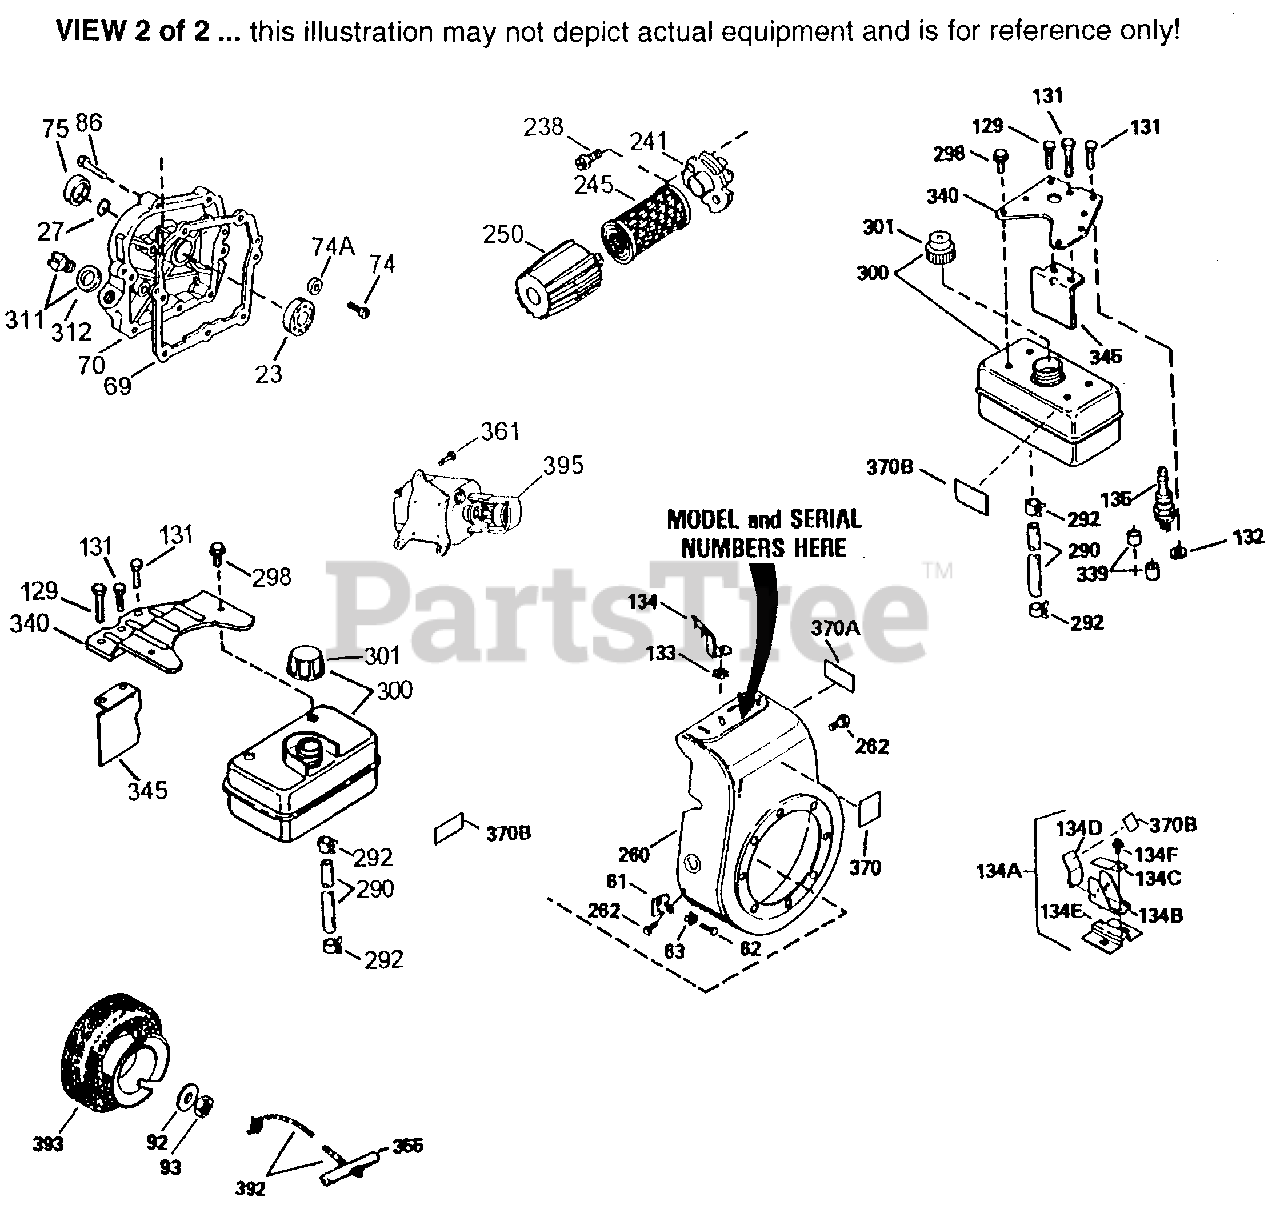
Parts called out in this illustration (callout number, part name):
19D	Extension Spring Ass'y. (Incl. 213)
23	Ball Bearing
27	Bearing Retainer
28	Lock Nut, 8-32
35	Screw, 10-32 x 3/4"
36	Lock Washer #8
37	Lock Nut, 10-32
38	Retaining Ring
64	Screw, T-30, 1/4-20 x 1/2"
64A	Washer
69	* Cylinder Cover Gasket
70	Cylinder Cover Incl. 72 thru 83 & 311
72A	Oil Drain Plug (Sq. hd., 1/4-18)
74	Screw, 10-24 x 9/16"
75	Oil Seal
86	Screw, 1/4-20 x 1-1/4"
92	Belleville Washer
93	Flywheel Nut
130A	Screw, 5/16-18 x 1-1/2"
130B	Screw, 5/16-18 x 1-1/2"
181	Screw, 1/4-28 x 1-11/16"
213	Screw, 10-32 x 3/8"
238	Screw, 8-32 x 3/8"
245	Air Filter (Paper) also available in Packaged Part #740029B
250	Air Cleaner Cover
260	Blower Housing
262	Screw, 1/4-20 x 1/2"
290	Fuel Line
292	Fuel Line Clamp
298	Screw, 1/4-15 x 7/8"
300	Fuel Tank (Incl. 292 & 301) (2 Quart)
301	Fuel Cap (Red)
311	Oil Fill Plug (Incl. 312) also availa ble in Packaged Part #740079
314	Screw, 1/4-20 x 3/4"
315	Alternator Coil (3 Amp) Incl. 321 thr u 323
322	Connector Body
323	Terminal
325	Wire Clip
340	Fuel Tank Bracket
345	Baffle Extension
361A	Screw, 1/4-20 x 5/8"
370A	Lubrication Decal
370K	Starter Decal
395	Electric Starter Motor (12 Volt)
